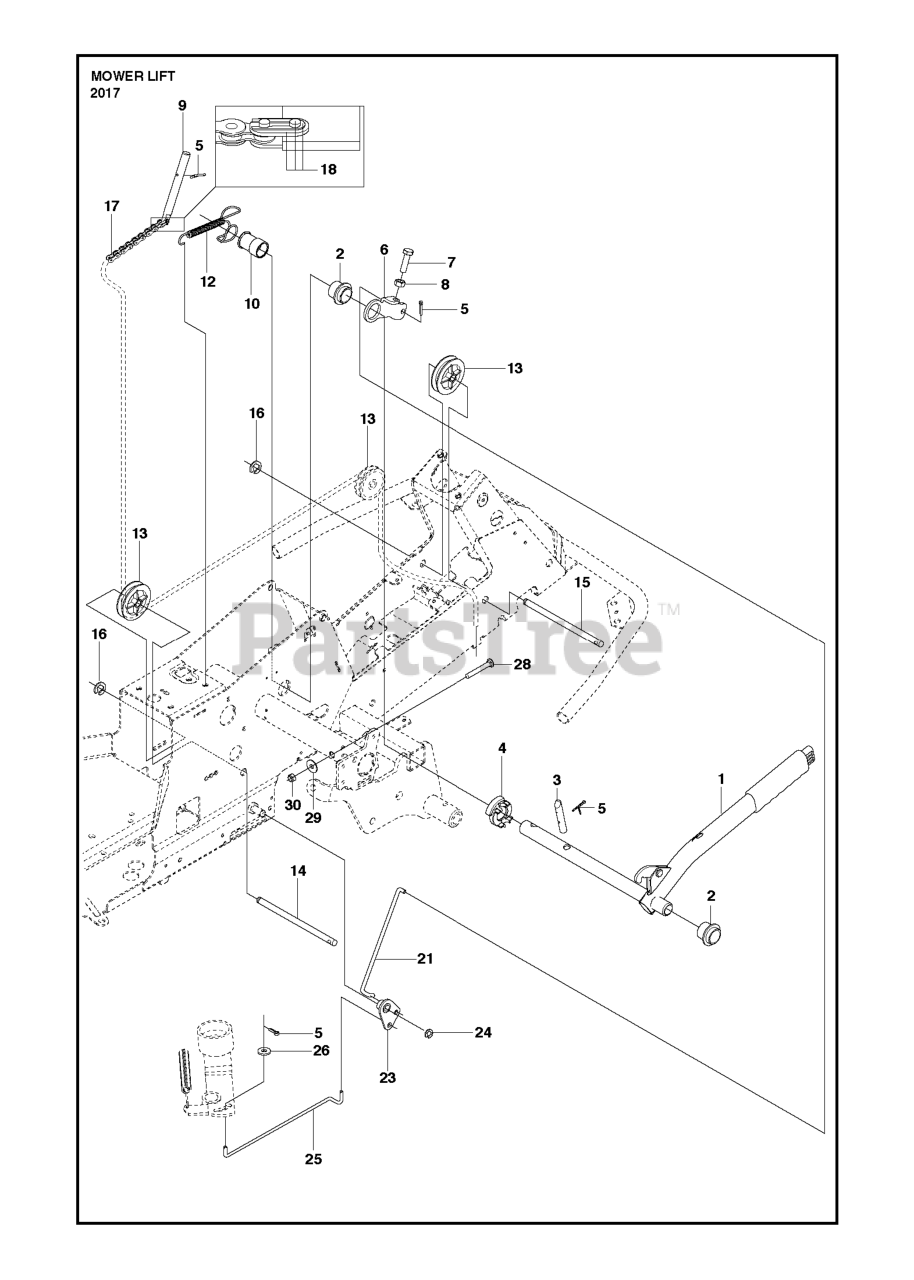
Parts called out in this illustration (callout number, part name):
6	LIFTING ARM LINK
21	CONNECTION ROD
24	RETAINING RING
25	CONNECTION ROD
29	WASHER BRB 8.4X17
30	LOCKNUT M8
